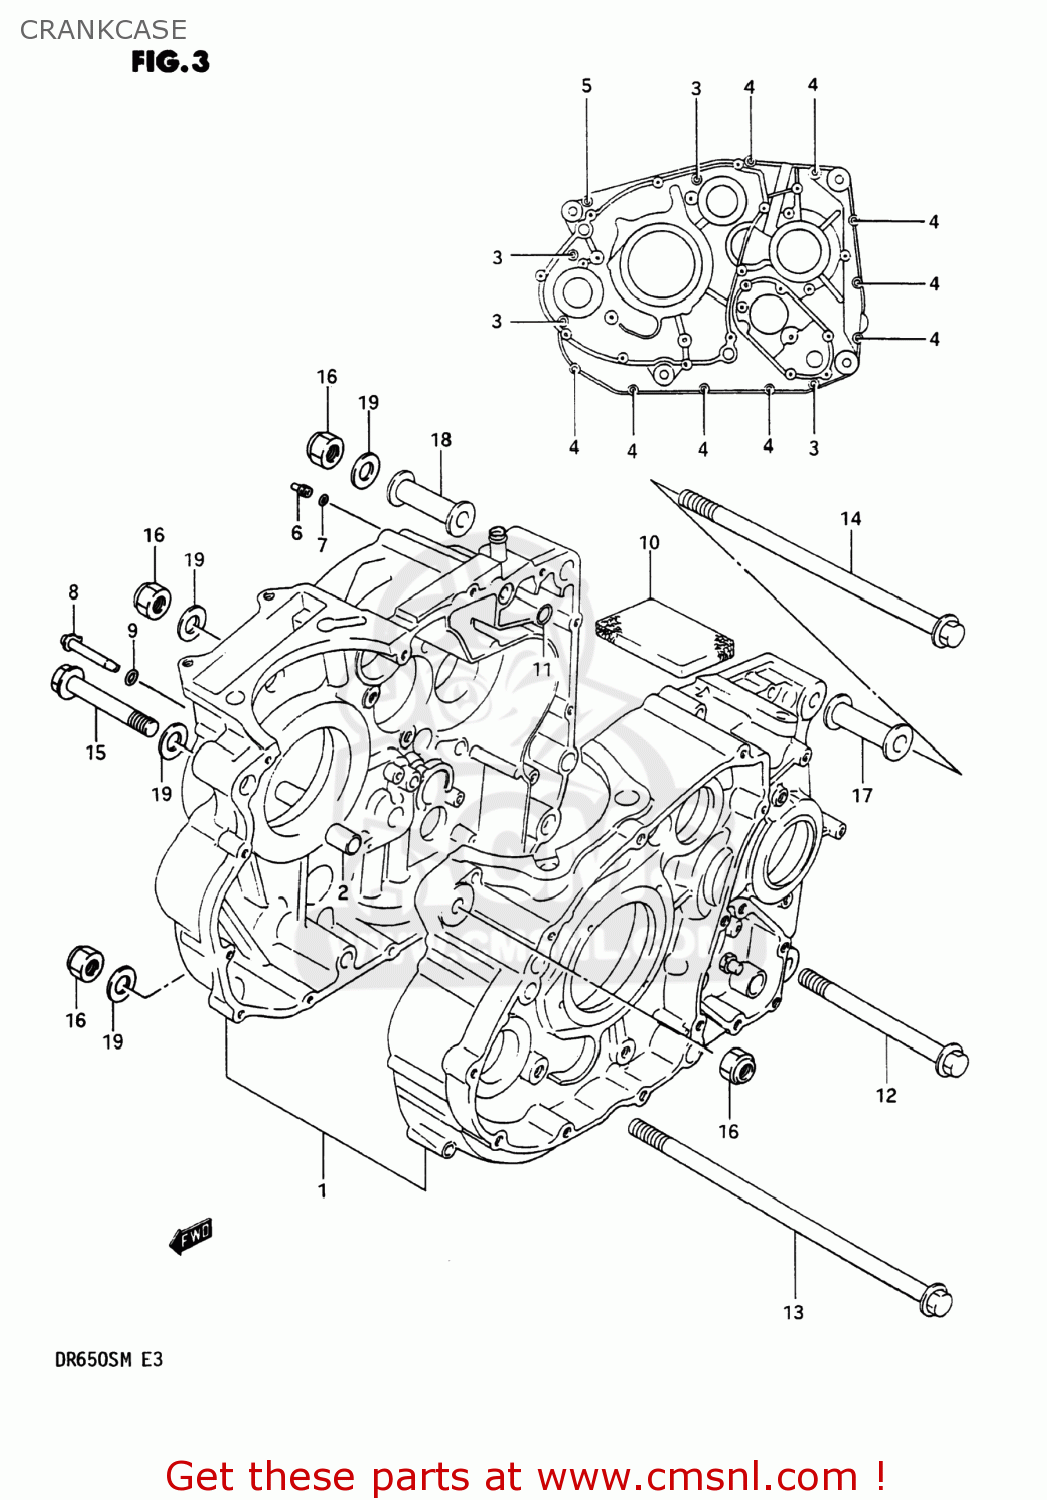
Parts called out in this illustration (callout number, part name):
1	CRANKCASE SET
2	PIN
3	BOLT (6X60)
4	BOLT 6X40
5	BOLT 6X30
6	JET(12)
7	O RING(D:1.2,ID:4)
8	PIPE,PISTON COOLING
9	O-RING
10	SEPARATOR,OIL BREATHER
11	O-RING
12	BOLT
13	BOLT
14	BOLT
15	BOLT
16	NUT (10MM)
17	SPACER,ENG MTG(L:55)
18	SPACER,ENGINE MOUNT(L:65)
19	WASHER 10MM
